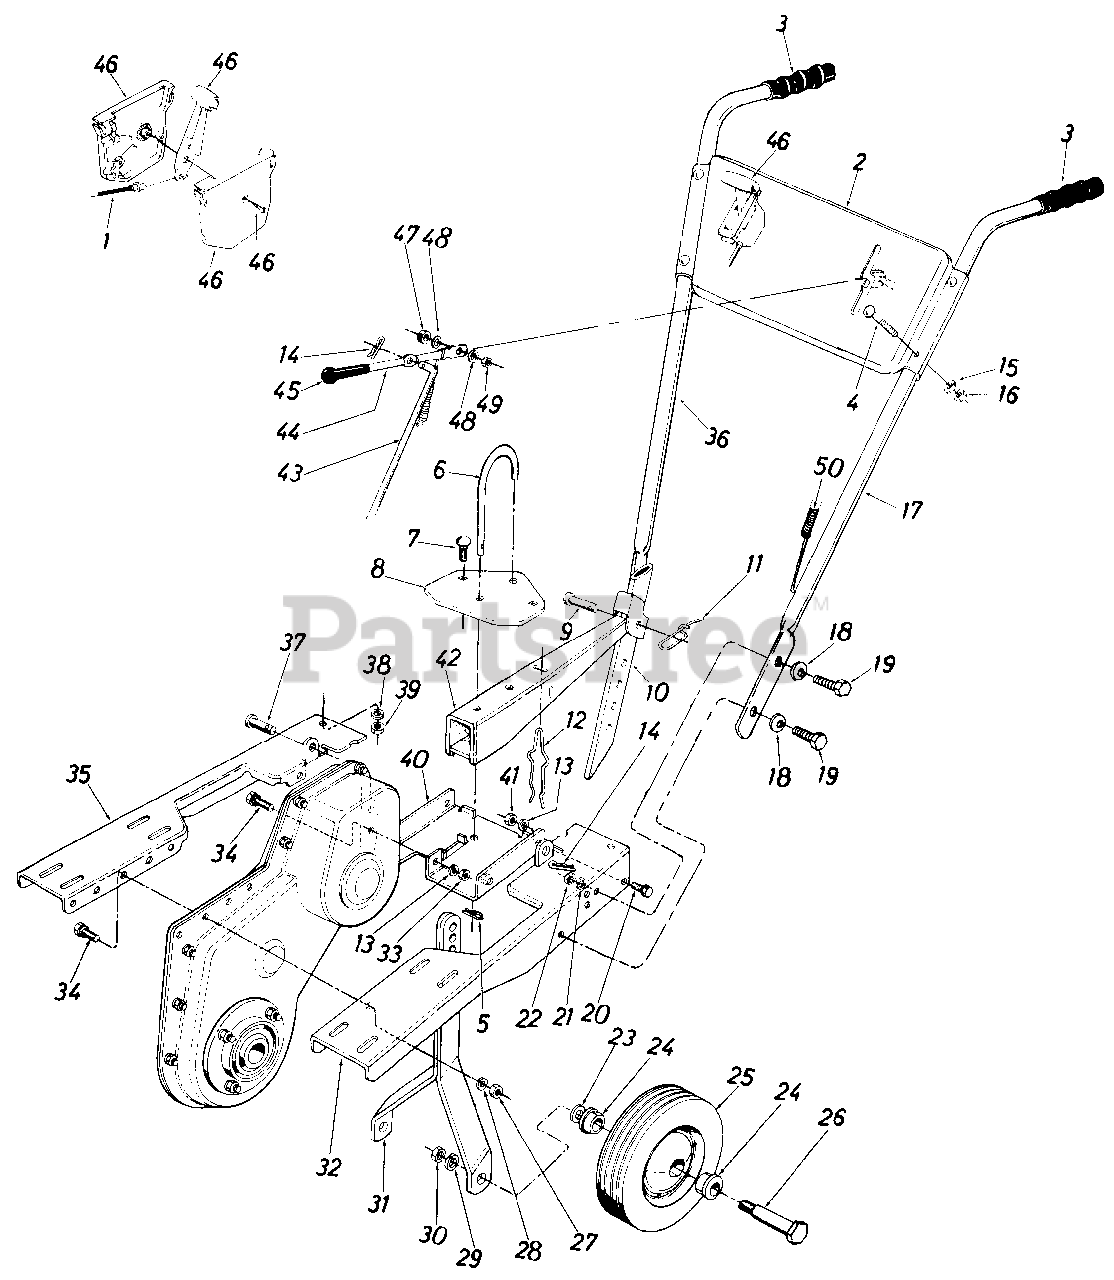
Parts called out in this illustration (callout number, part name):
1	Throttle Control Wire - 35"
2	Handle Panel Ass'y.
3	Handle Grip
4	Carriage Bolt 5/16-18 x 1.75" Lg.
5	Internal Cotter Pin
6	"U"-Clevis Pin .500" Dia.
7	Carriage Bolt 5/16-18 x .75" Lg.
8	"U"-Channel Plate
9	Clevis Pin .500" Dia.
10	Depth Bar
11	Spring Pin
12	Depth Bar Spring
13	L-Wash. 5/16" I.D.
14	Internal Cotter Pin
15	L-Wash. 5/16" I.D.
16	Hex Nut 5/16-18 Thd.
17	Handle - L.H.
18	Belleville Wash. 3/8" I.D.
19	Hex Bolt 3/8-16 x 1.00" Lg.
20	Hex Bolt 5/16-18 x .75" Lg.
21	L-Wash. 3/8" I.D.
22	Hex Nut 3/8-16 Thd.
23	Belleville Wash. .505 I.D. x 1.00" O.D.
24	Fl. Bearing w/Flats .631 I.D.
25	Wheel Ass'y. Comp. 10 x 1.75
26	Shoulder Bolt .625" Dia. x 2.75" Lg.
27	Hex Nut 5/16-18 Thd.
28	L-Wash. 5/16" I.D.
29	L-Wash. 1/2" I.D.
30	Hex Ins. L-Nut 1/2-20 Thd.
31	Wheel Bracket Ass'y.
32	Engine "U"-Channel Ass'y. - L.H.
33	Hex Nut 5/16-18 Thd.
34	Hex Sems Bolt 5/16-18 x 1.00" Lg.
35	Engine "U"-Channel Ass'y. - R.H.
36	Handle - R.H.
37	Clevis Pin
38	L-Wash. 5/16" I.D.
39	Hex Nut 5/16-18 Thd.
40	"U"-Channel Bracket Ass'y.
41	Hex Nut 5/16-18 Thd.
42	Tailpiece Ass'y.
43	Control Rod
44	Clutch Lever
46	Throttle Control Box Ass'y.
47	Rubber Wash.
48	Fl-Wash. .344" I.D. x .880 O.D. x .06
49	Hex Cent. L-Nut 5/16-18 Thd.
50	Extension Spring .75" O.D. x 11.0" Lg.
